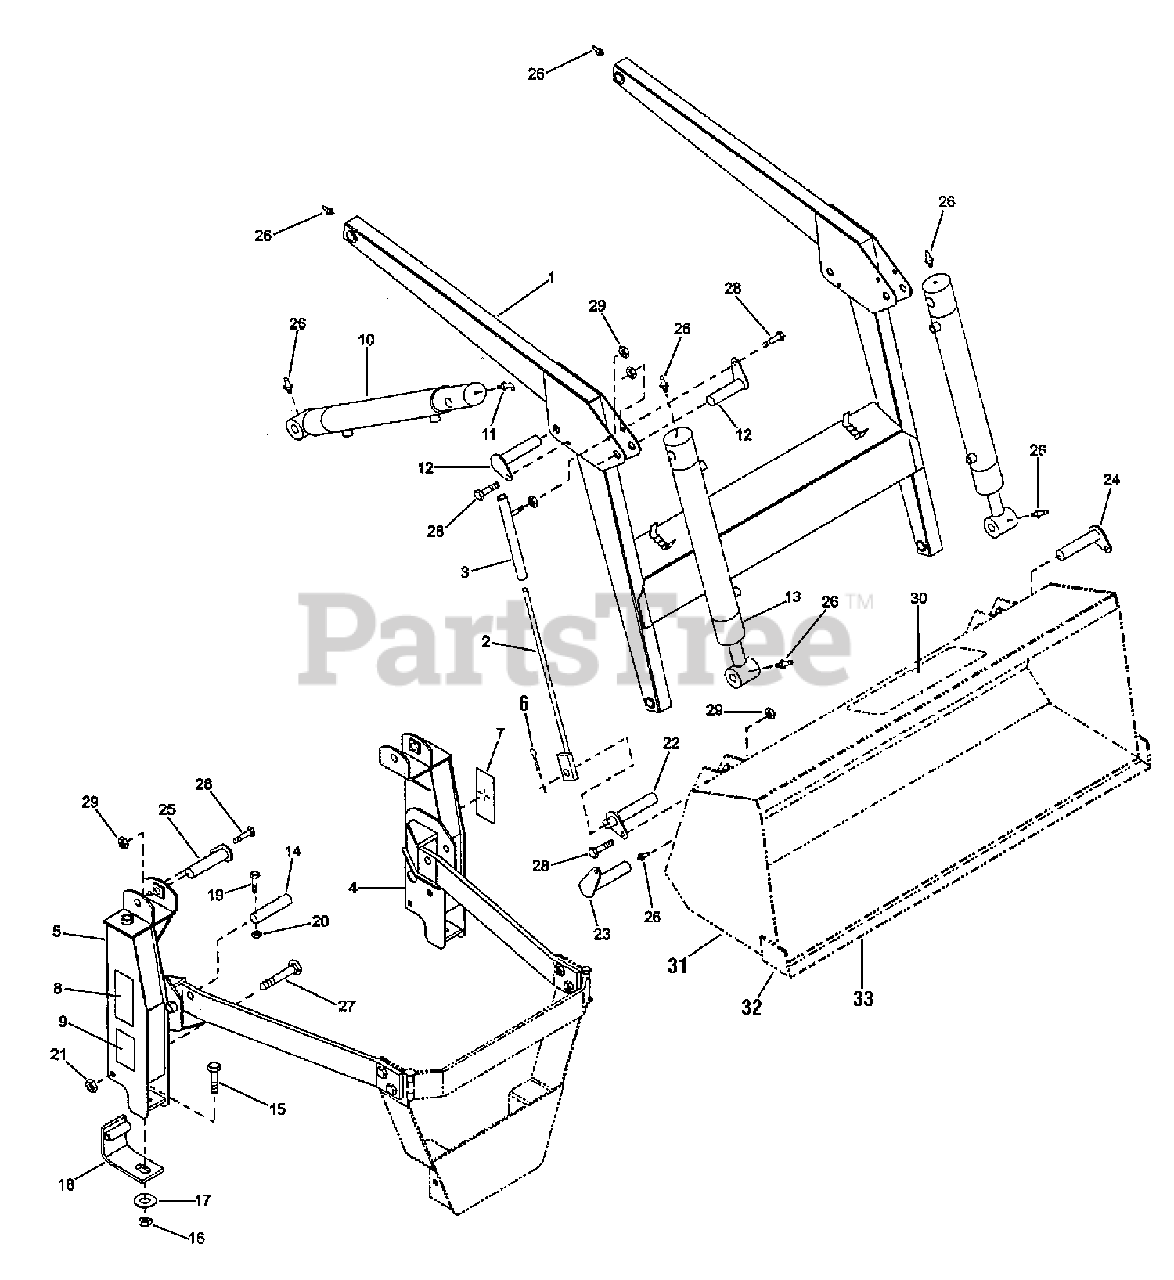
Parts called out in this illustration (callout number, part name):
2	ROD, Indicator
3	GUIDE TUBE, Indicator Rod
4	SIDE FRAME, Left
5	SIDE FRAME, Right
6	PIN, Cotter, 5/32 x 1-1/2
7	DECAL, Warning
8	DECAL, Warning
9	DECAL, Caution
10	CYLINDER, Lift (See SERVICE PARTS - Lift Cylinder)
11	FITTING, Grease
12	PIN, Cylinder Base, 3/4 x 2-1/2
13	CYLINDER, Bucket (See SERVICE PARTS - Bucket Cylinder)
14	PIN, 3/4 x 4
15	CAPSCREW, Hex Head, 1/2-13 x 2
16	LOCKNUT, Hex, 1/2-13
17	WASHER, 1/2
19	CAPSCREW, Hex Head,1/4-20 x 1-1/4
20	LOCKNUT, Hex,1/4-20
21	LOCKNUT, Hex, 5/8-11
22	PIN, 3/4 x 3-1/4
23	PIN, 3/4 x 3-1/4
24	PIN, 3/4 x 3-1/4
25	CAPSCREW, Hex Head, 1/2-13 x 2
26	FITTING, Grease, 1/4-28
27	CARRIAGE BOLT, 5/8-11 x 3-1/2
28	SHOULDER BOLT, 3/8-16 x 1
29	LOCKNUT, Hex, 3/8-16
30	DECAL, Caution
32	CUTTING EDGE, Side (Weld on part)
33	CUTTING EDGE, Bottom, 48" (Weld on part)
